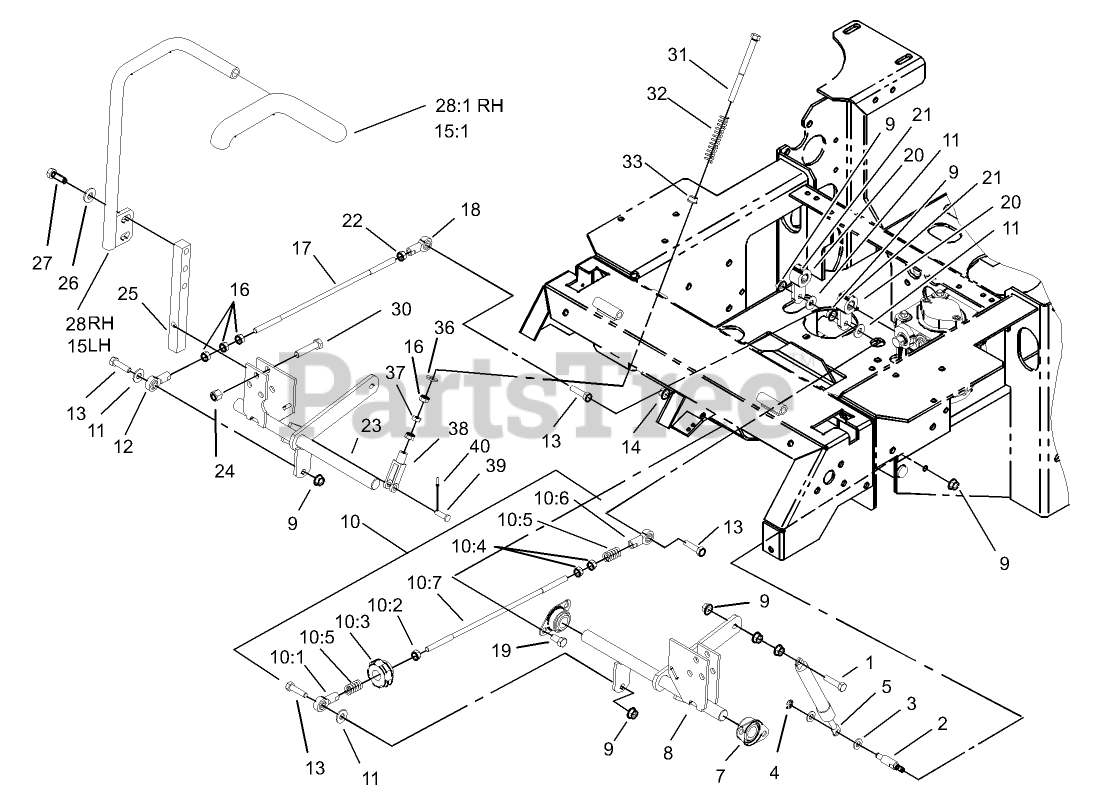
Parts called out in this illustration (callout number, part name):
1	SCREW-HH
2	PIN-DAMPER
3	WASHER-PLAIN
4	RING-RETAINING, EXT
5	Damper-Control, Motion
7	BEARING-FLANGE, SIDE
8	LH Motion Control ASM
9	NUT-HF
10	Tracking Rod ASM
10:1	BALLJOINT-RH
10:2	NUT-HEX
10:3	KNOB-TRACKING
10:5	SPRING-COMPRESSION
10:6	BALLJOINT-LH
10:7	Link-Rod, Tracking
11	WASHER-FLAT
12	BALLJOINT-RH
13	SCREW-HH
14	NUT-HHF, WHIZ
15	LH LEVER ASM
15:1	GRIP-CONTROL, MOTION
16	NUT-HEX
17	Link-Rod, Tracking
18	BALLJOINT-LH
19	SCREW-HH
20	ARM-CONTROL
21	SCREW-SET
23	RH Motion Control ASM
24	NUT-LOCK, NI
25	ARM-SHAFT, CONTROL
26	WASHER-BELLEVILLE
27	SCREW-HH
28	RH LEVER ASM
28:1	GRIP-CONTROL, MOTION
30	SCREW-HH
31	BOLT-RETURN, NEUTRAL
32	SPRING-RETURN, NEUTRAL
33	BUSHING-FLANGED
36	WASHER-FLAT
37	NUT-JAM
38	YOKE-ADJUSTABLE
39	PIN-CLEVIS
40	PIN-COTTER
